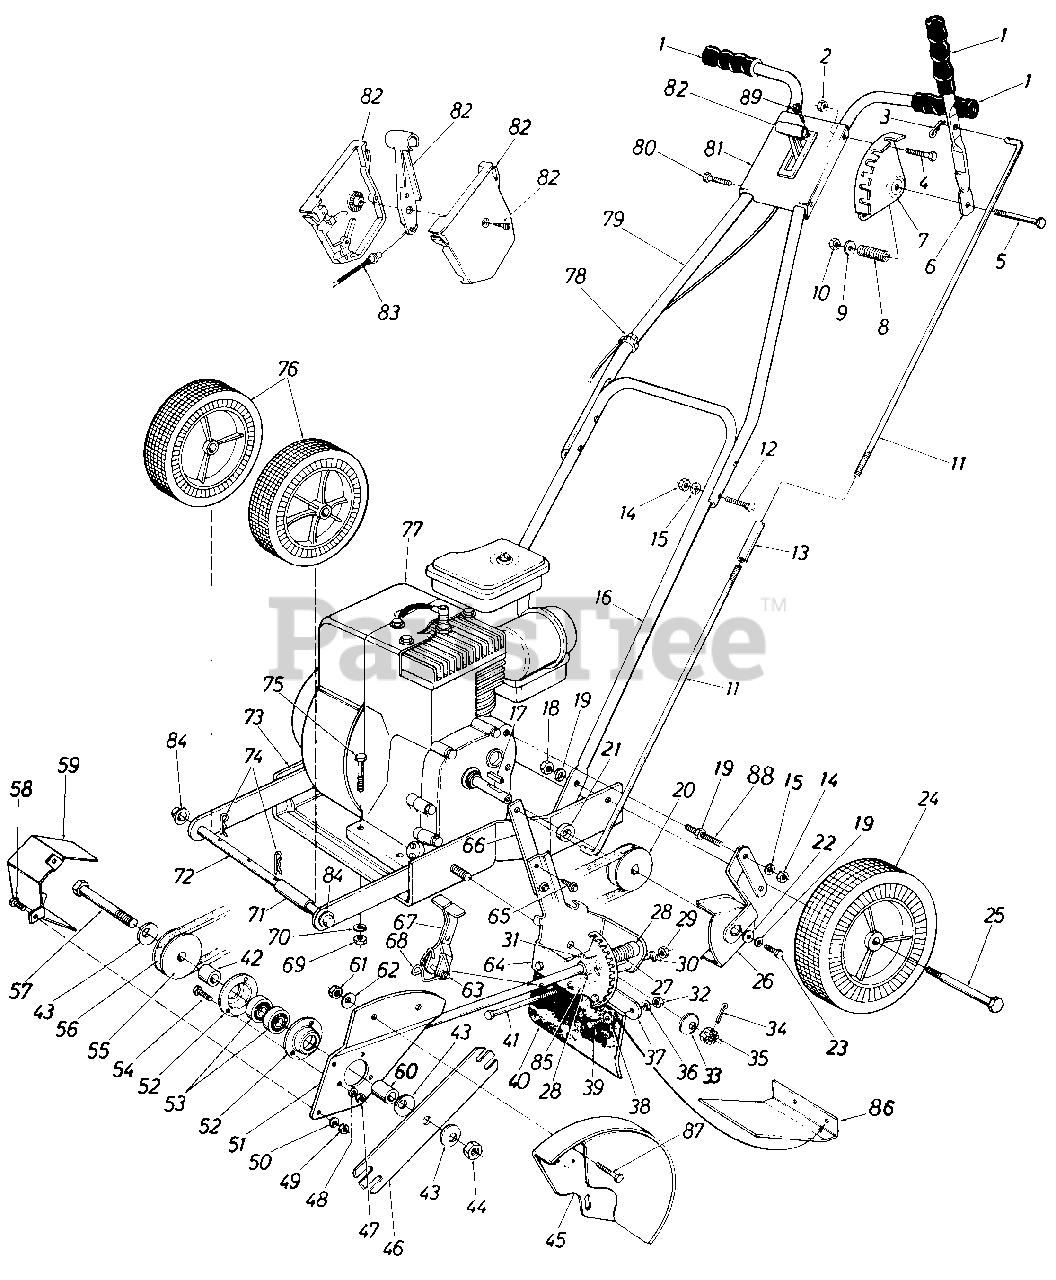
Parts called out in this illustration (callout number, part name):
1	Black Grip
2	Hex L.-Nut 1/4-20 Thd.
3	Cotter Pin 1/8" Dia. x 1.00" Lg.
4	Hex Bolt 1/4-20 x 1.25" Lg.
5	Hex Bolt 5/16-18 x 1.75" Lg.
8	Compression Spring .50" O.D. x 1.38" Lg.
9	Fl.-Wasn. .344" I.D. x .62" O.D. x .063
10	Hex Cent. L.-Nut 5/16-18 Thd.
11	Clutch Rod Half 3/8" Dia. x 18.25" Lg.
12	Carriage Bolt 1i4 20x 1.25" Lg.
13	Rod Aljustlnent Link
14	Hex Nut 1/4-20 Thd.
15	L.-Wash. 1/4" I.D.
16	Lower Handle
17	Sq. Key 3/16" x 3/16" x .75" Lg.
18	Hex Nut 3/8-16 Thd.
19	L.-Wash. 3/8" I.D.
20	Engine Pulley
21	Spacer.75" I.D.
22	Fl.-Wash. .385" I.D. x 1.0" O.D.
23	Hex Bolt 3/8-24 x 1.0" Lg.
24	Rear Wheel Ass'y. 8 x 1.75
25	Shoulder Bolt .498" Dia. x 1.45" Lg.
26	Belt Guard Ass'y .
27	Compression Spring
28	Bushing
29	Hex Nut 5/16-18 Thd.
30	L.-Wash. 5/16" I.D.
31	Spring Pin Spir. 3/16" Dia. x 1.00" Lg.
32	Hex Nut 1/4-20 Thd.
33	Bell.-Wash. .535" I.D. x 1.50"0.D.
34	Cotter Pin 1/8" Dia. x 1.00" Lg.
35	Hex Slotted Nut 1/2-20 Thd.
36	L.-Wash. 1/4" I.D.
39	Hex Bolt 1/4-20 x .50" Lg.
41	Hex Bolt 5/16-18 x 4.5" Lg.
42	Spacer .635" I.D. x .88" I.D. x 1.030" Lg.
43	Bell.-Wash. .630" I.D. x 1.25" O.D.
44	IHex Ins. L.-Nut 5/8-18 Thd.
47	Hex Nut 1/4-20 Thd.
48	L.-Wash. 1/4" I.D.
49	Hex Nut 1/4-20 Thd.
50	L.-Wash. 1/4" I.D.
53	Ball Bearing .62" I.D. x 1.38" O.D.
54	Hex Bolt 1/4-20 x.62" Lg.
55	3/8" "V"-Pulley 2" x 5/8" I.D.
56	"V"-Belt
57	Hex Bolt 5/8-18 x 4.50" Lg.
58	Hex Bolt 1/4-20 x .50" Lg.
60	Sleeve .632" I.D. x .875" O.D. x.90" Lg.
61	Hex Nut 5/16-18 Thd.
62	Bell.-Wash. .345" I.D. x .88" O.D.
63	Spring Pin Spir. 1/4" Dia. x 2.00" L
68	Torsion Spring
69	Hex Nut 5/16-18 Thd.
70	L.-Wash. 5/16" I.D.
71	Spacer .50" I.D. x .62" O.D. x 1.62" Lg.
72	Axle .50" Dia. x 8.75" Lg.
73	Base Ass'y.
74	Hair Pin Cotter 1/2" Dia.
75	Hex Bolt 5/16-18 x 1.50" Lg.
76	Front Wheel Ass'y. 7 x 1.50
77	Engine
78	Cable Tie
79	Upper Handle
80	Hex Bolt 1/4-20 x 1.00" Lg.
81	Handle Support Pl ate
82	Throttle Control Box Ass'y.
83	Throttle Control Wire 30" Lg.
84	Push Cap 1/2" Dia.
85	Spacer .386" I.D. x .510" O.D. x 3.765" Lg.
88	1 Stud 1/4-20 x 2.12" Lg.
89	Self-Tap Scr. #10 x .50" Lg.
